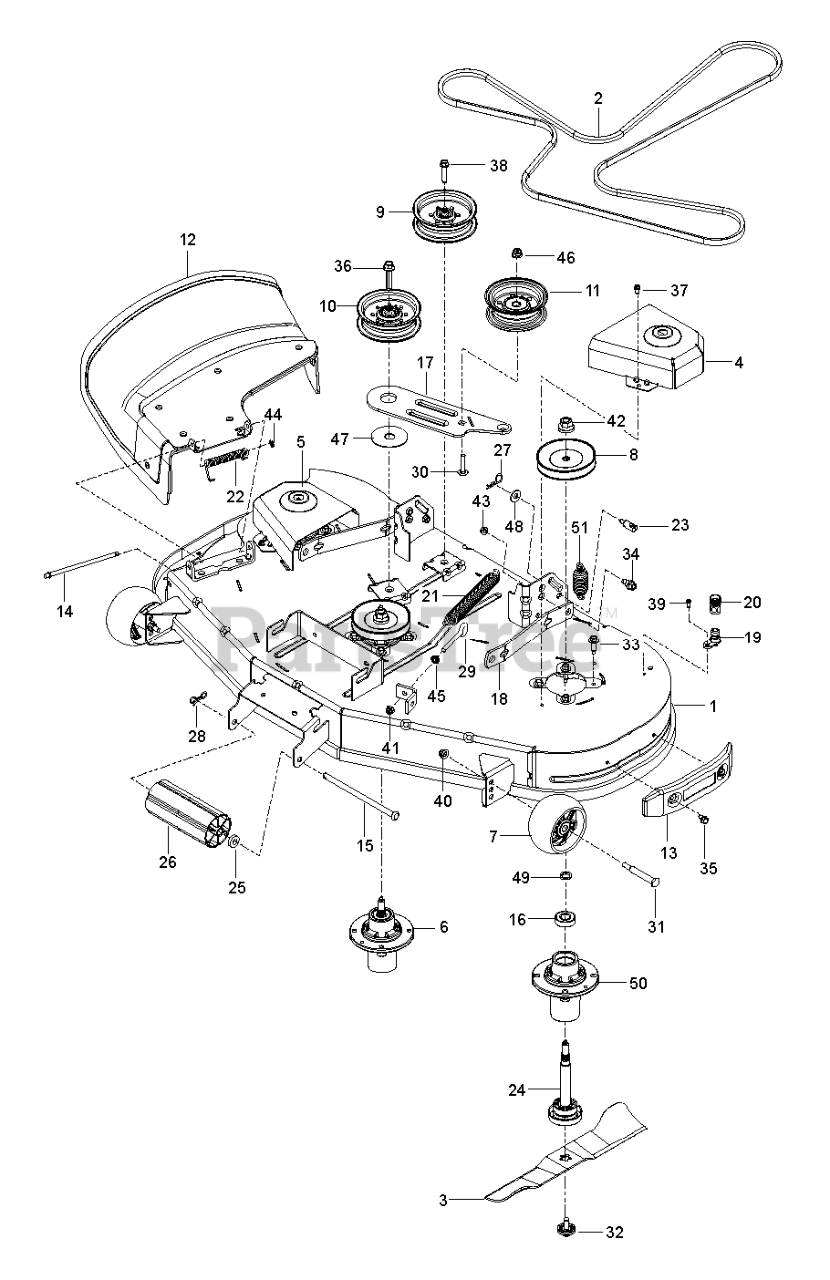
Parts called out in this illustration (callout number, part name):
1	DECK SVC.48.CC.RZ 668
3	BLADE.BAGGER.RES.CLRCT.48".BLK
4	COVER.PNT.MANDREL.LH.ZTR.GREY
5	COVER.PNT.MANDREL.RH.GREY
6	MANDREL ASM, CAST IRON
7	WHEEL.GAUGE.RALLY
8	MANDREL.PULLEY.38.BRIGHT.ZINC
9	BELT SHIELD - L.H. ORANGE
10	PULLEY.IDLER.MWR.STATI.LH
11	PULLEY.IDLER.48"PRIMARY
12	DEFLECTOR.ASM.48".CLRCT.RES.OR
13	BUMPER 48 CLEARCUT TRIM SIDE A
17	ARM.PNT.CLUTCHING.EDIP
18	ARM.RFIXED.MOWER.SUSPNSIONX431
19	PORT.WASHOUT
20	COUPLING.QUICK CONNECT
21	SPRING.EXTENSION
22	SPRING.42.FCS.DEFLECTOR
23	STUD.W/"D"ANTI-ROTATION
24	SHAFT ASM MANDREL
25	BUSHING.NOSE.ROLLER
26	NOSE ROLLER 48"
27	PIN.COTTER.7/16.BOW TI.
28	PIN.COTTER.5/16.BOW TI
29	GSPW Bolts
32	BOLT.WASHER.ASM.7/16-2
33	BOLT.HEX.WASHR.HED.313-18X1.19
34	BOLT.SHOULDER
35	SHOULDER BOLT 5/16-18TT
36	SCREW.7/16-14 X 2.125.WASHER
37	SCREW.1/4-20X5/8
38	BOLT;HEX_3/8-16 X 1.78.CLRZINC
41	NUT HEXAGON FLANGE 5/16-18 ST
42	BOLT.SHOULDER.3/8-16X3-5/8.
44	NUT PUSH M
45	GSPW Hardware
46	NUT LOCK FLG 3/8-16 UNC
49	WASHER.SPACER.MANDREL
50	MANDREL, HOUSING - CAST IRON
